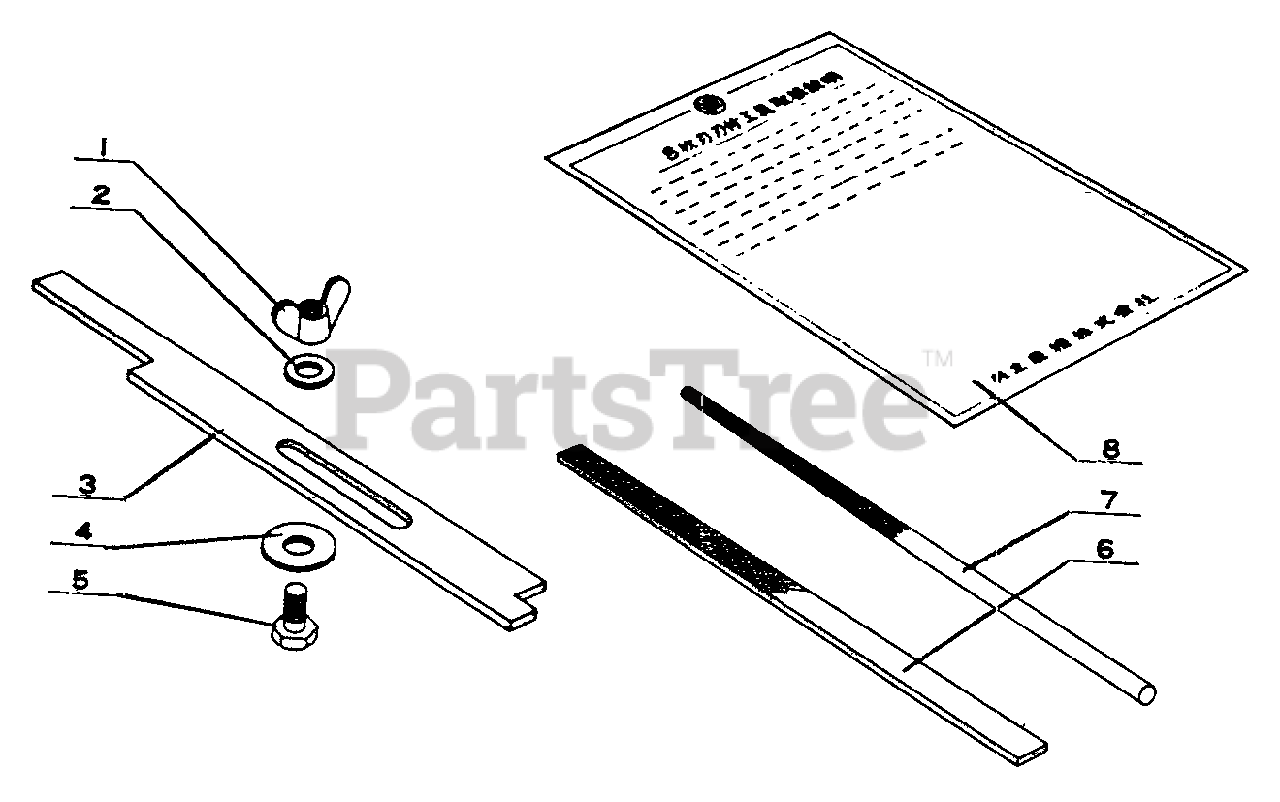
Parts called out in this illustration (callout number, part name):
1	NUT - BUTTERFLY
2	WASHER 8.5×16×1.2
3	FILING GAUGE
4	WASHER, FILING GAUGE
6	FLAT FILE
7	ROUND FILE
8	OWNER'S MANUAL
